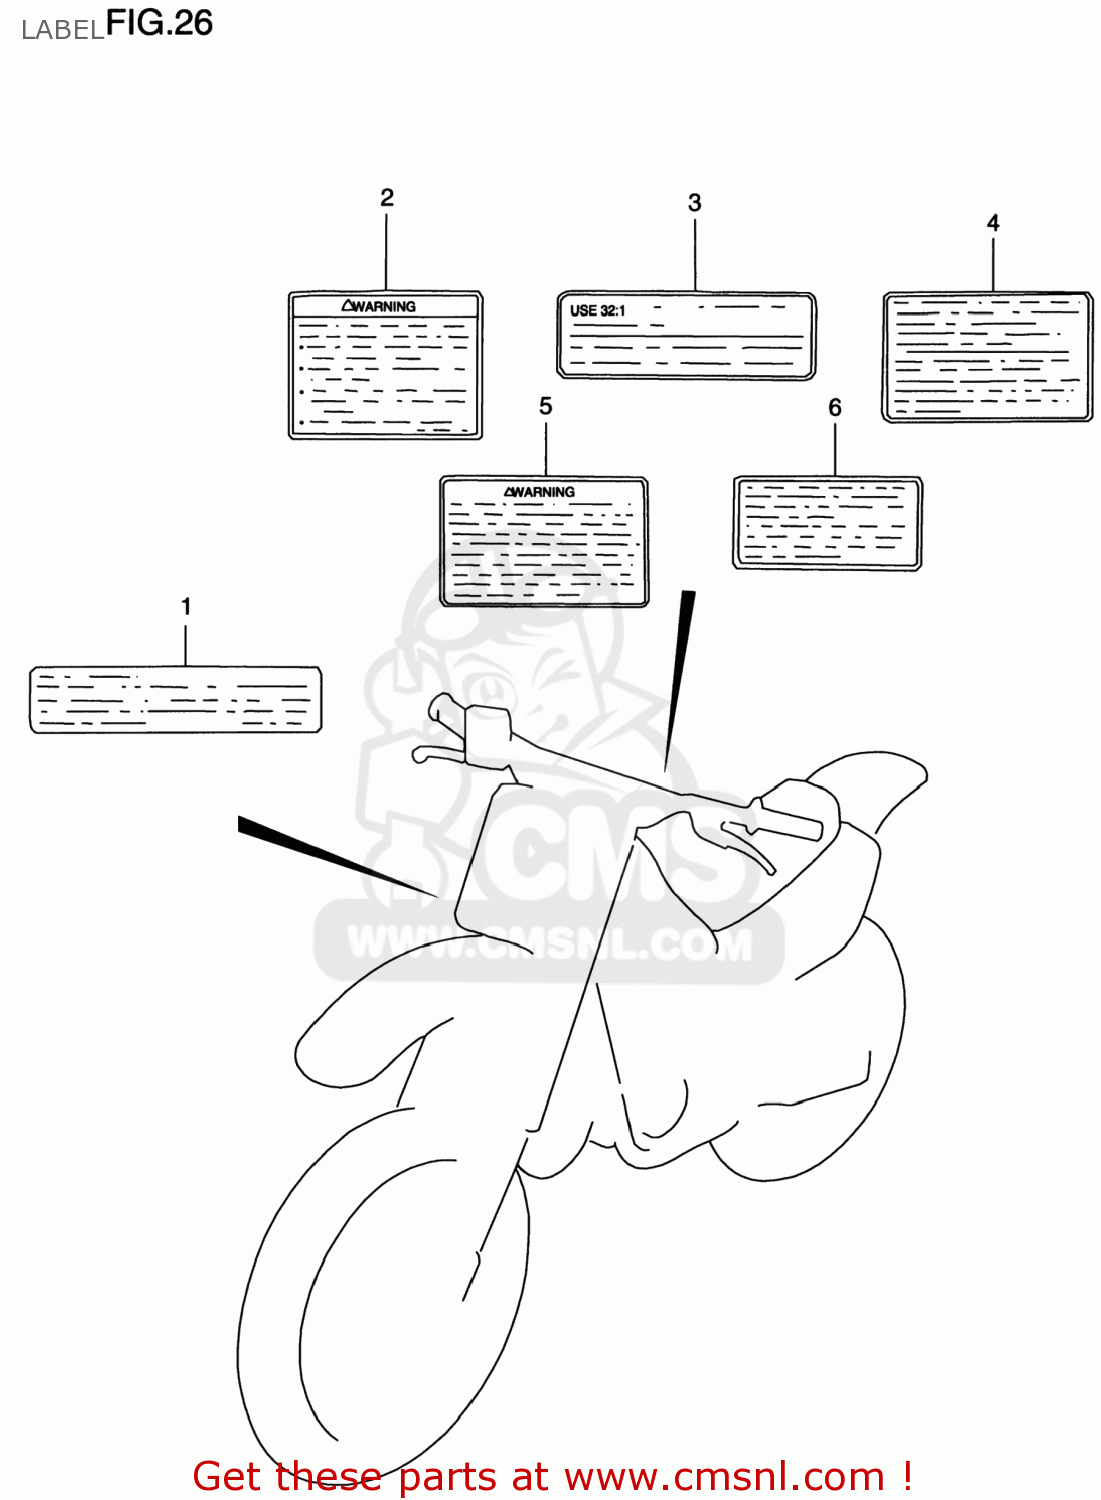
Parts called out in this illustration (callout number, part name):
1	PLATE,WARNING
2	LABEL,GENERAL WARNING
3	LABEL,WARNING NO.2
4	LABEL,WARNING
5	LABEL,WARNING
6	LABEL (MANUAL NOTICE)
7	MANUAL, OWNER'S
